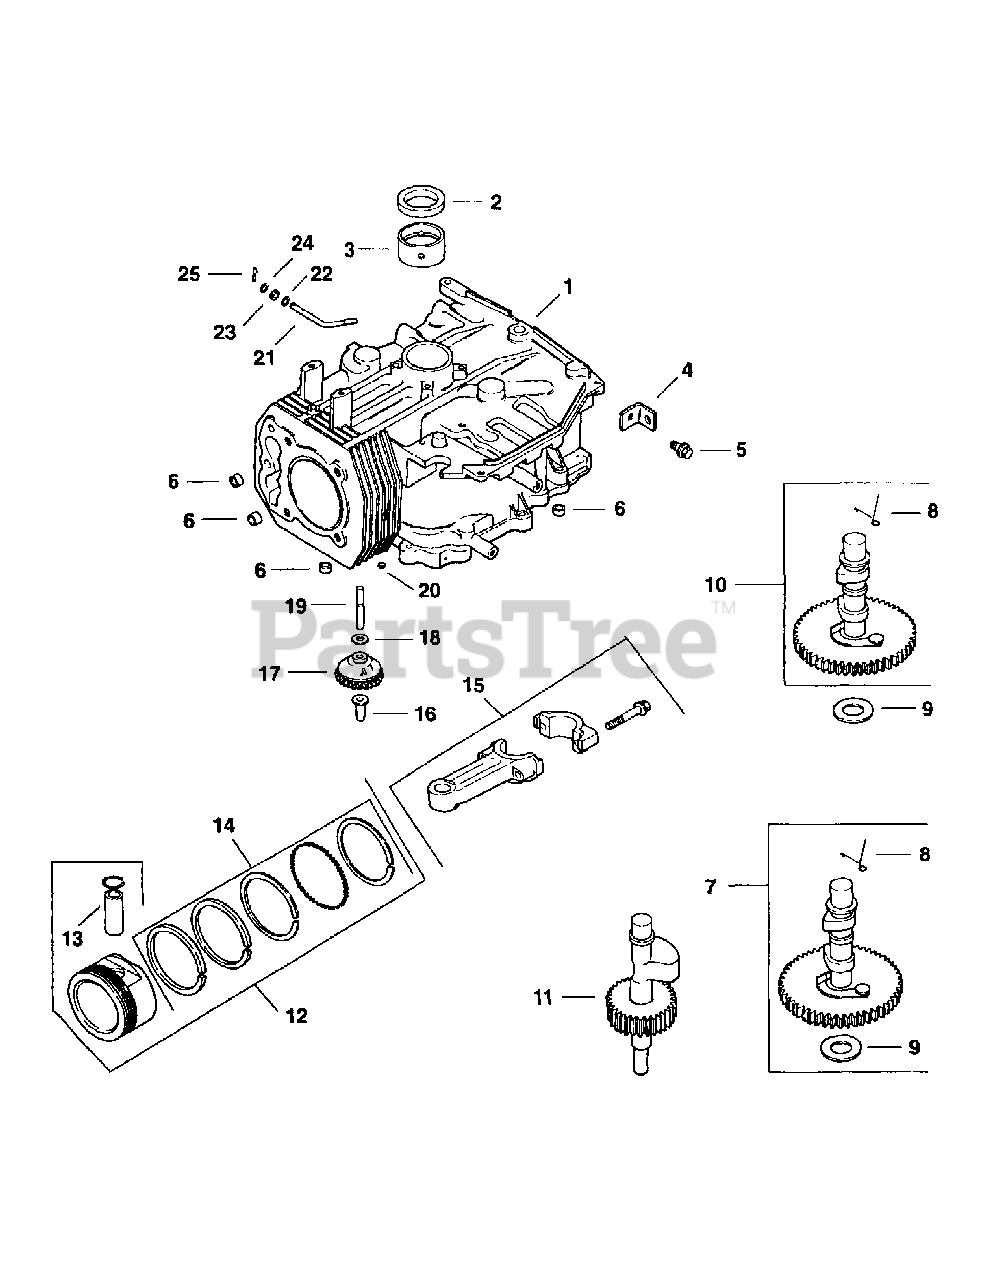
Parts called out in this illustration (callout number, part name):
1	Crankcase
2	Seal, Crankshaft
3	Bearing, Crankshaft (Std.)
3	Bearing, Crankshaft (.25)
3	Bearing, Crankshaft (.50)
4	Strap, Lifting
5	Screw, Lifting Strap M8 x 1.25 x 25
6	Dowel, Locating
7	Kit, Camshaft
8	Spring, Actuating (ACR)
9	Shim, Camshaft (A.R.) (White)
9	Shim, Camshaft (A.R.) (Blue)
9	Shim, Camshaft (A.R.) (Green)
9	Shim, Camshaft (A.R.) (Yellow)
9	Shim, Camshaft (A.R.) (Red)
9	Shim, Camshaft (A.R.) (Gray)
9	Shim, Camshaft (A.R.) (Black)
11	Shaft, Balance
12	Piston w/Ring Set (Std.)
12	Piston w/Ring Set (.25)
12	Piston w/Ring Set (.50)
13	Retainer, Piston Pin
14	Ring Set (Std.)
14	Ring Set (.25)
14	Ring Set (.50)
15	Connecting Rod (Std.)
15	Connecting Rod (.25)
16	Pin, Governor Regulating
17	Gear, Governor
18	Washer, Governor Gear Thrust
19	Shaft, Governor Gear
20	Plug, Cup
21	Governor Cross Shaft Kit
22	Washer, Plain 1/4"
23	Seal, Governor Cross Shaft
24	Washer, Governor Shaft
25	Pin, Governor Hitch
